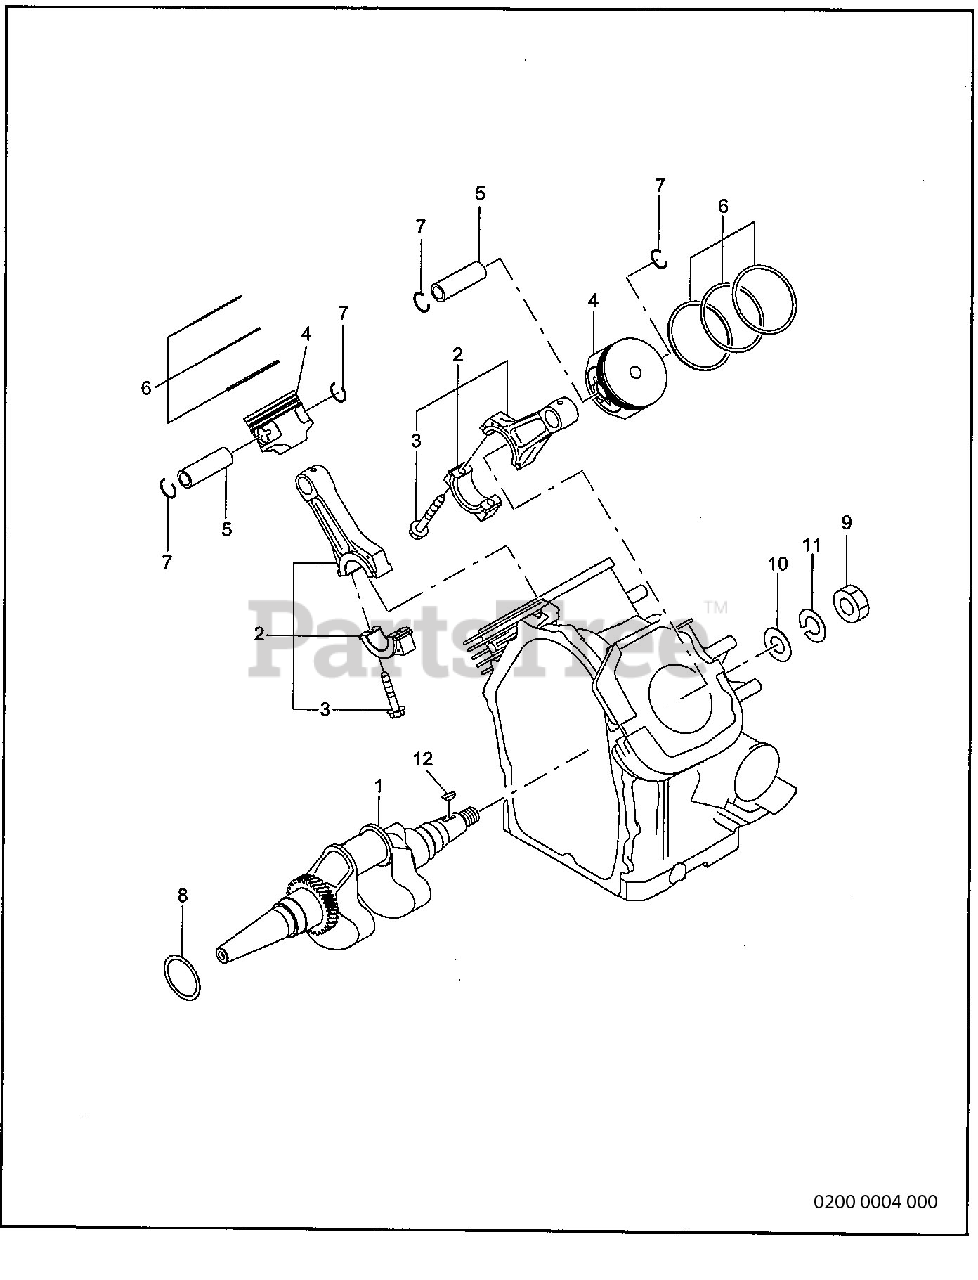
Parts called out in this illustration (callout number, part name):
1	CRANKSHAFT ASSY
2	CONNECTING ROD ASSY
3	CONNECTING ROD BOLT
4	PISTON (over size 0.25mm)
4	PISTON (over size 0.50mm)
6	PISTON RING SET (STD)
6	PISTON RING SET (over size 0.25mm)
6	PISTON RING SET (over size 0.50mm)
